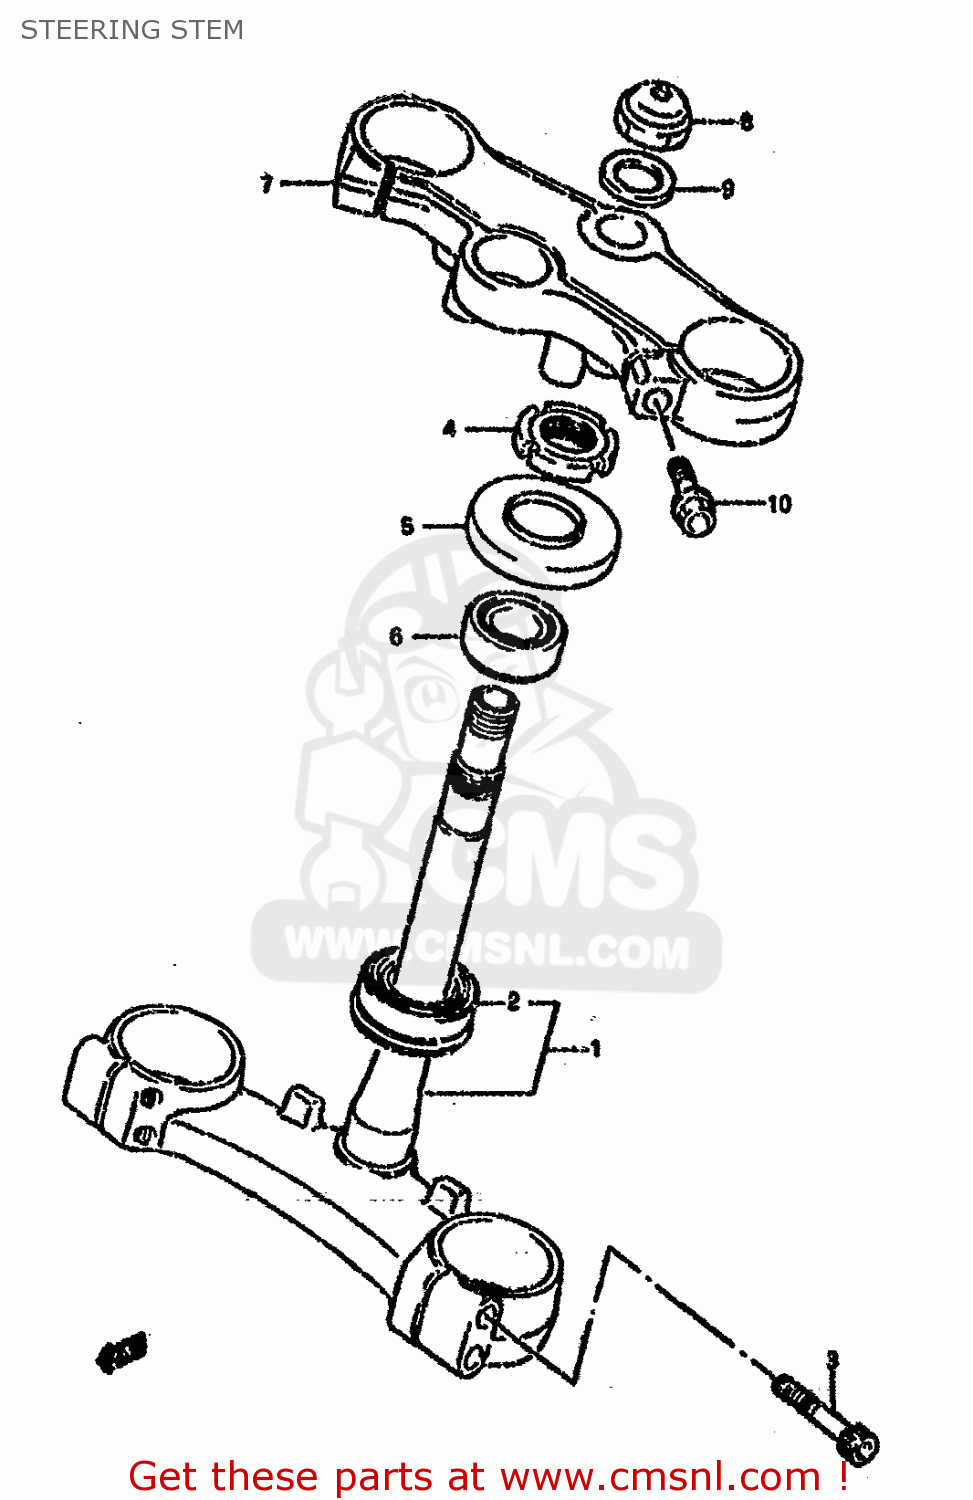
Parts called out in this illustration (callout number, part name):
1	STEM,STEERING
2	BEARING(30X55X17)
3	BOLT
4	NUT,STEERING STEM(25X44X10)
5	SEAL,OIL(34X69X11.9)
6	TAPER,ROLLER BEARING
7	HEAD,STEERING STEM
8	NUT
9	WASHER(22.5X32X1.6)
10	BOLT
